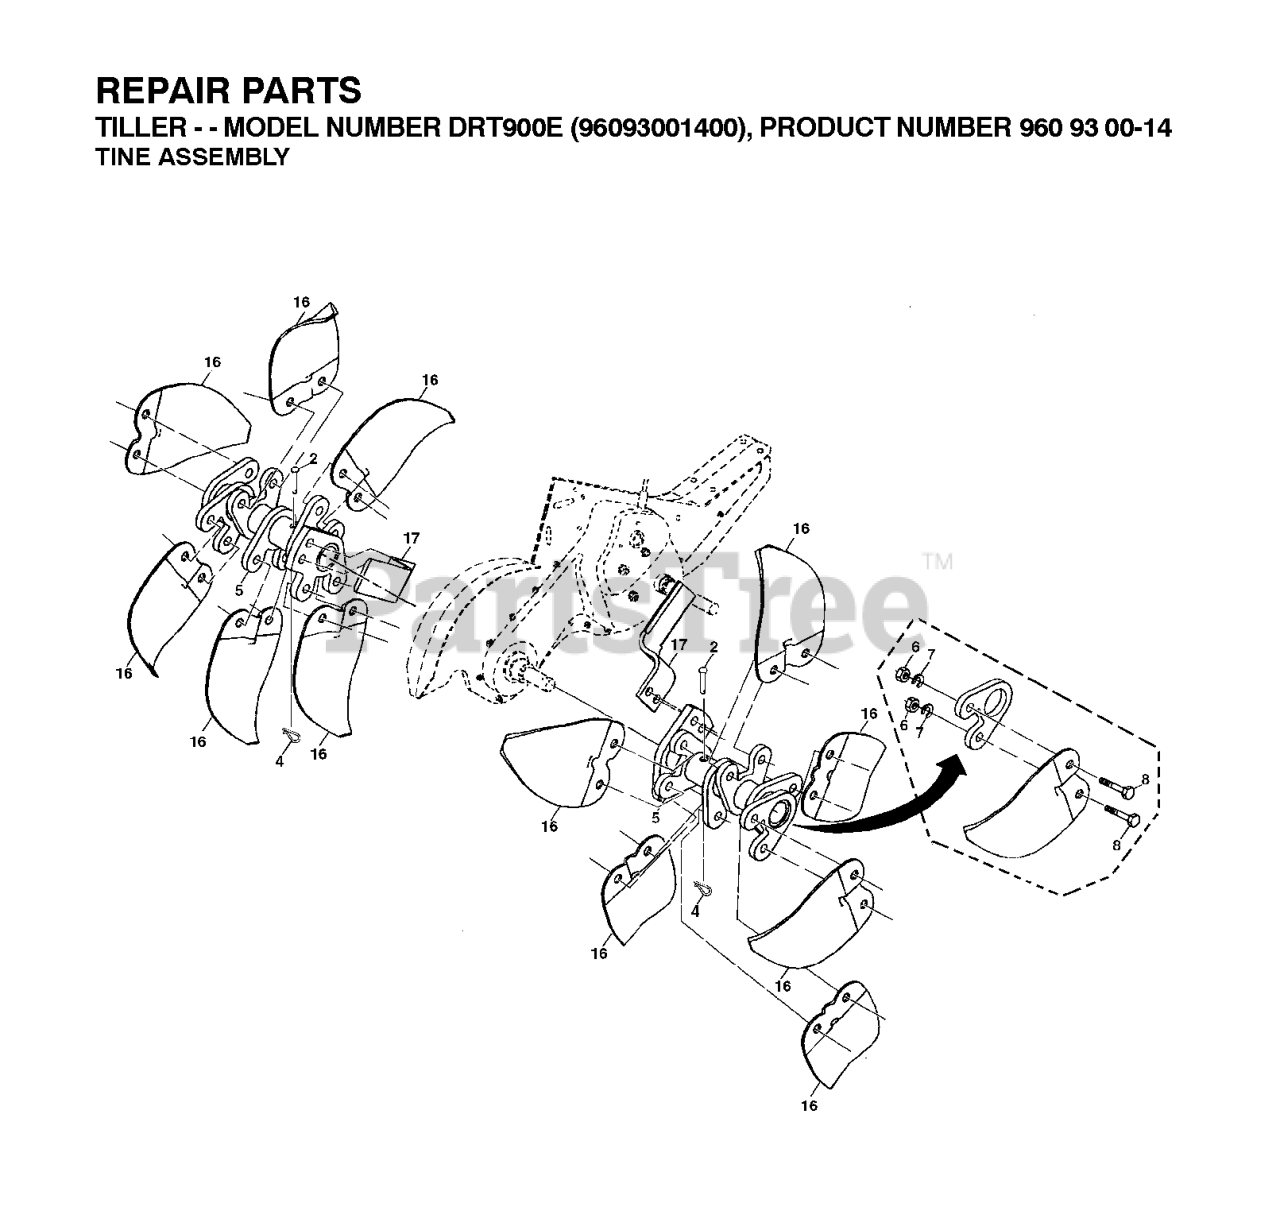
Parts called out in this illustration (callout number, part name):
2	PIN RETAINING SCREW
4	SPRING RETAINER
5	HUB.ASM.DRT17.2004 (CMPL KIT)
6	NUT
7	WASHER, LOCK 3/8
8	BOLT.HEX.001X20.37-24X1.ZINC
16	TINE.SPADE
17	TINE.CLEANING BLACK
